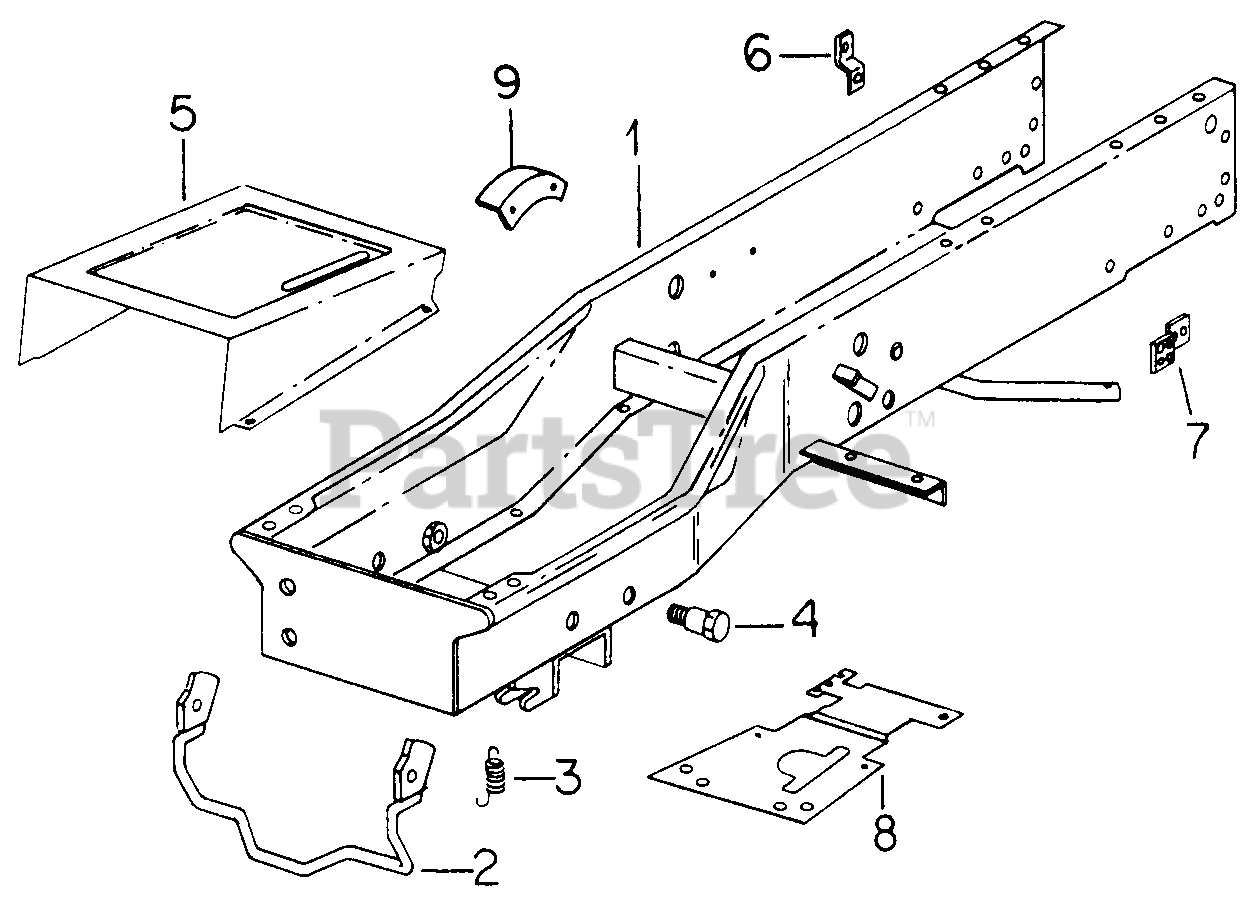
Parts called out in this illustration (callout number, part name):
3	Spring, Latch
4	Bolt, Implement Mtg Shoulder
5	Cover w/Product Graphic
6	Bracket, Trans Mounting
6	Bracket, Trans Mounting, RH Serial Number 720000 and Above)
7	Bracket, Trans Mounting, LH
9	Bracket, Indicator
